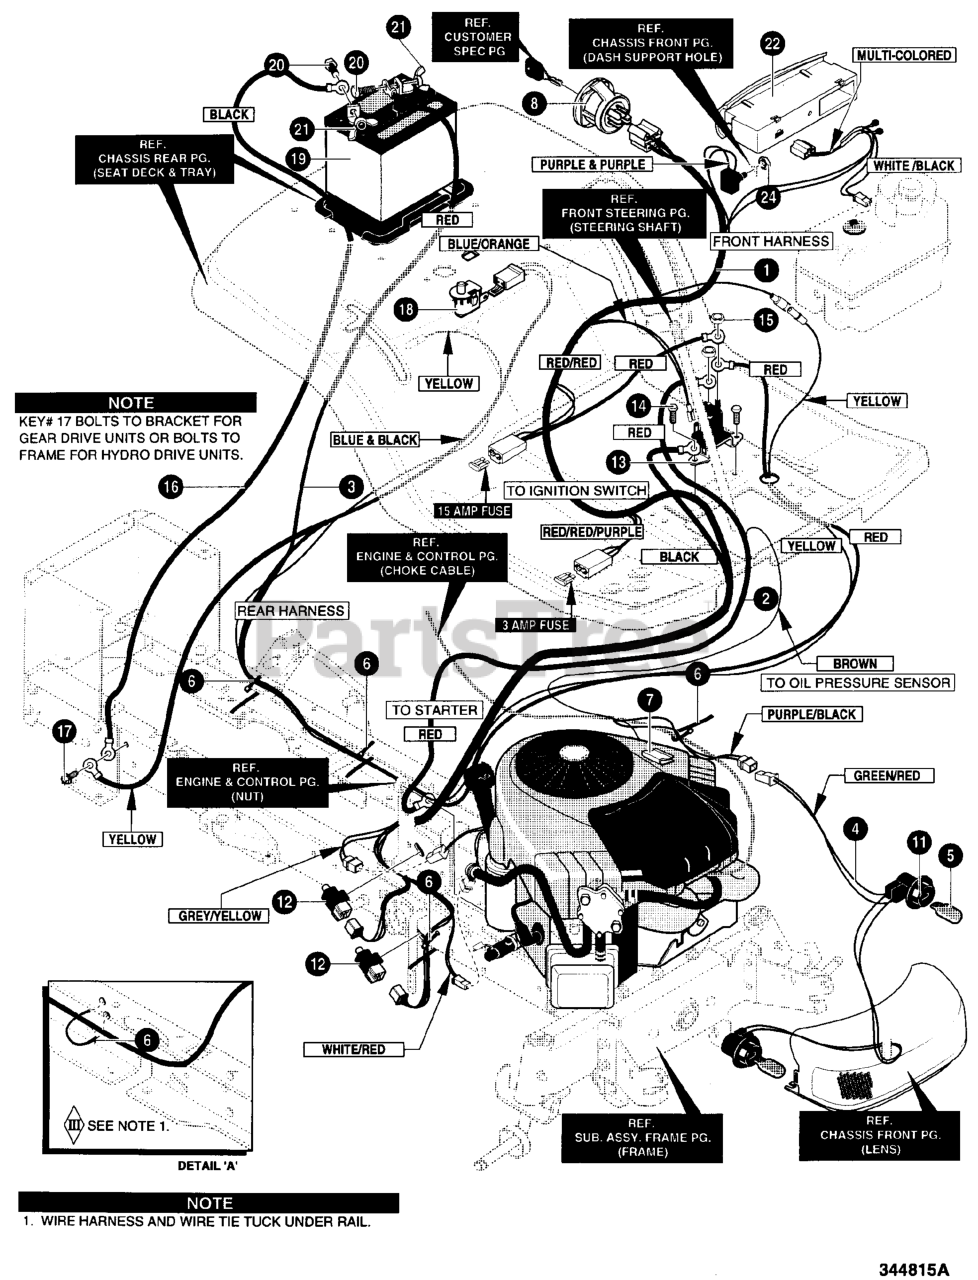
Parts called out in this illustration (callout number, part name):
1	WIRE HARNESS
2	WIRE, SOLENOID LEAD TO STARTER
3	WIRE HARNESS, REAR 20HP
4	WIRE ASSEMBLY, HEADLIGHTS
5	BULB, LIGHT
6	TIE, CABLE
7	WIRE CLIP, ADHESIVE
8	SWITCH, IGNITION
11	SOCKET, LAMP
12	SWITCH, SAFETY
13	SOLENOID
16	WIRE, GROUND
18	SWITCH, SEAT
19	BATTERY
20	BOLT, 1/4-20X.63
21	NUT, WING 1/4-20
22	ELECTRONIC DIAG
24	NUT, PLASTIC
